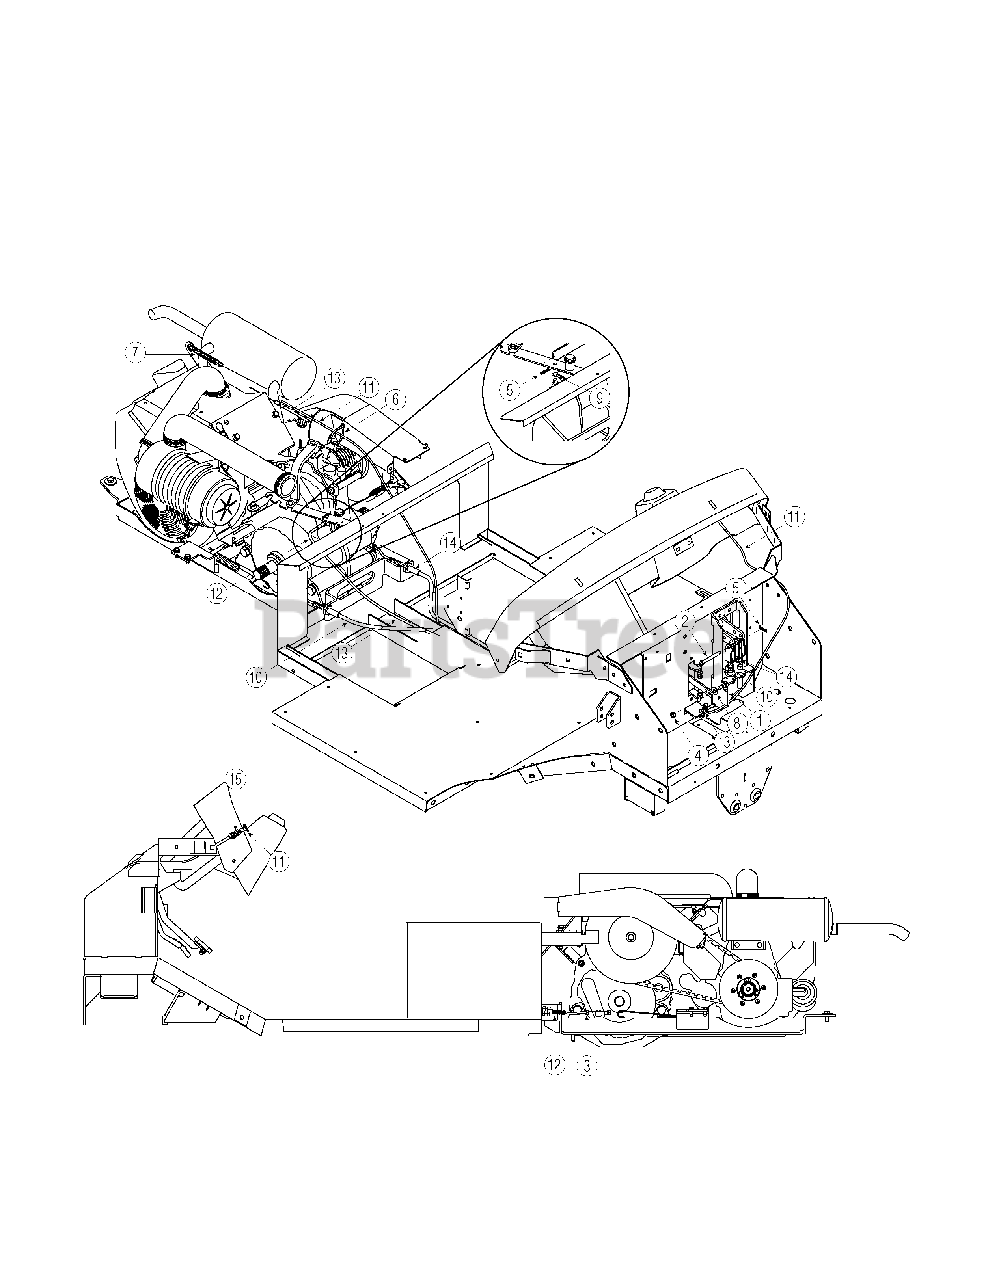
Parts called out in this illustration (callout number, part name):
1	Screw, Shoulder, .375 x .375
2	Pin, Clevis, 5/16 x 2.5
3	Nut, Jam, 5/16-24, Gr5
4	Nut, Hex Lock, 5/16-18
5	Pin, Cotter, .072 x 1.13
6	Cable Tie, Tree Mount
7	Extension Spring
8	Washer, .349 x .879 x .063
9	Washer, Spring, .317 x .879 x .063
10	Cable, Control, Brake
11	Cable, Control, Choke
12	Cable, Control, Clutch Brake
13	Cable, Control, Throttle
14	Cable, Control, Brake
15	Nut, Jam Lock 3/16-16, Gr5
